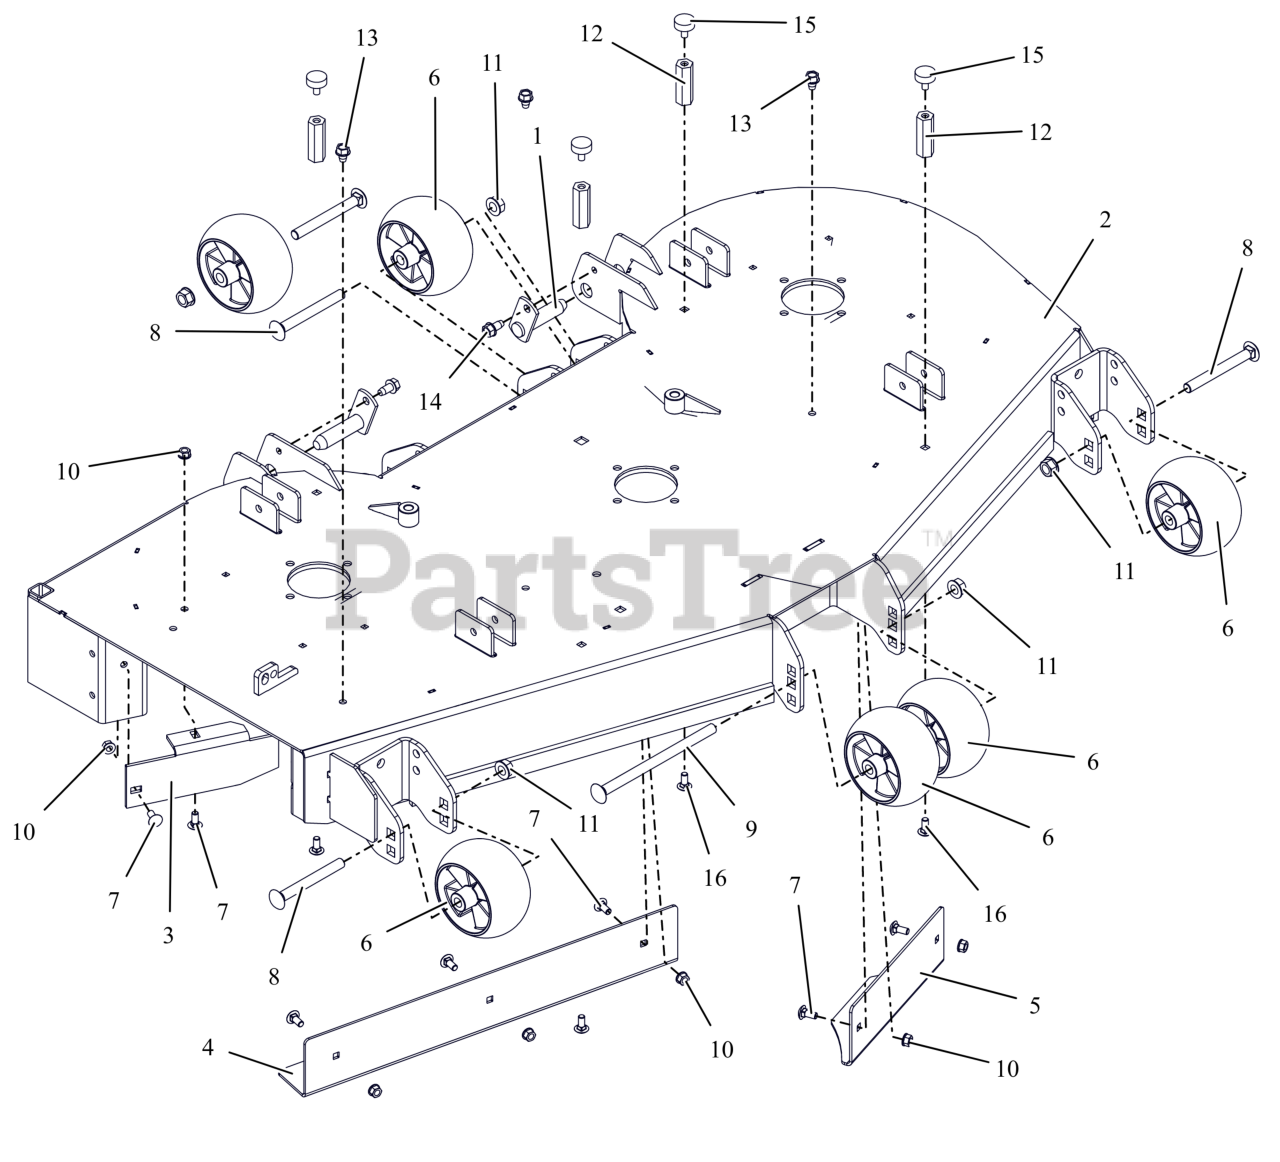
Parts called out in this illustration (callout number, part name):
1	WLDMT, MOWER MTG. PIN (BLACK)
2	KIT, 52" PRO-WALK DECK W/ DECALS (RED)
3	52" DISCHARGE BAFFLE - RED
4	BAFFLE, 52" RH VACUUM (RED)
5	BAFFLE, 52" LH VACUUM (RED)
6	WHEEL, ANTI SCALP - 5X3 CTR W/RIBS
7	BLT,RHSN .31-18X.75 G5 ZCC
8	BLT,RHNS .50-13X4.50 G5 ZCC NS
9	BLT,RHSN .50-13X8.00 G5 ZCC NS
10	NUT,LK-CTR-FLG .31-18 GF ZCC
11	NUT-LK-CTR-FLG .500-13 GG ZCC
12	NUT, .31-18X2.25 LG COUPLING
13	SCR,TAP .375-16X.50 HWH TR ZCC
14	SCR,TAP .375-16X.75 HWH TR ZCC
15	BUMPER, RUBBER
16	BTL,RHSN .313-18 X 0.75 G5 ZCC LT
